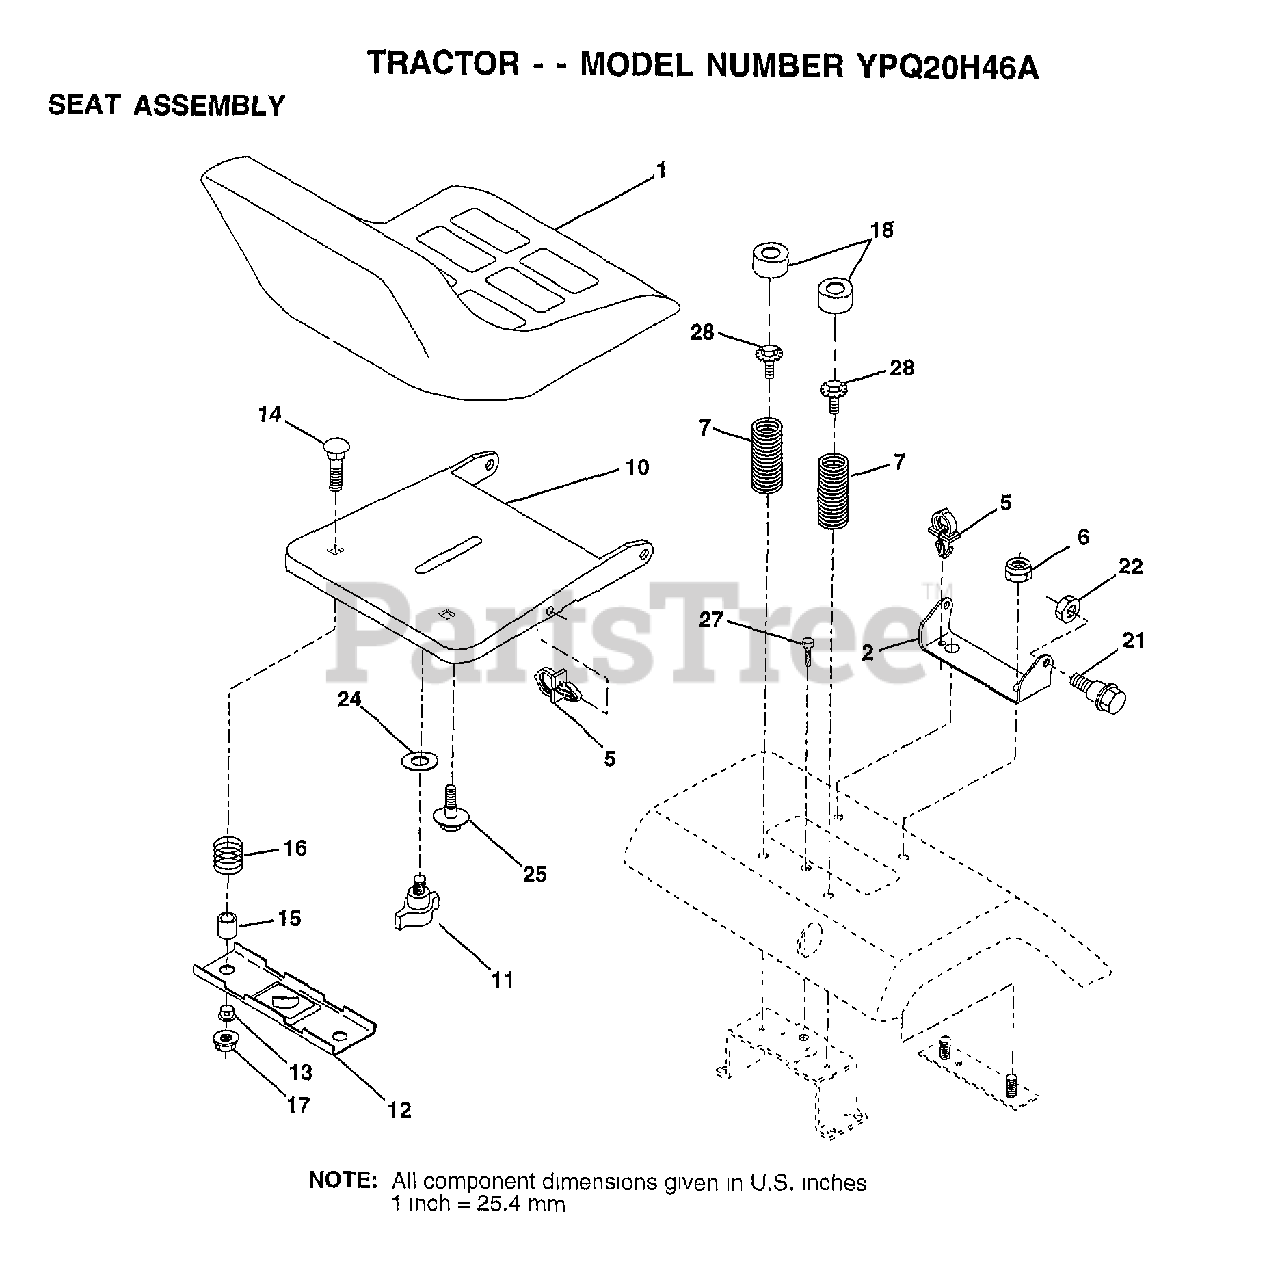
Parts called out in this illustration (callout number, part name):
1	SEAT.2500/1516.BK
2	BRACKET PVT SEAT
5	CLIP.PUSH-IN.HING
6	NUT
7	SPRING COMPRESSIO
10	PAN-SEAT
11	KNOB.SEAT.ADJ.WINGNUT
12	BRKT SWITCH
13	BUSHING
14	BOLT-RD HD SQ NK
15	SPACER SPLIT
16	SPRING COMPRESSED
18	CAP SPRING
21	"BOLT,SHOULDER"
22	NUT
24	WASHER
25	"BOLT,SHOULDER"
27	SCREW LT
28	BOLT.5/16-18.UNC
